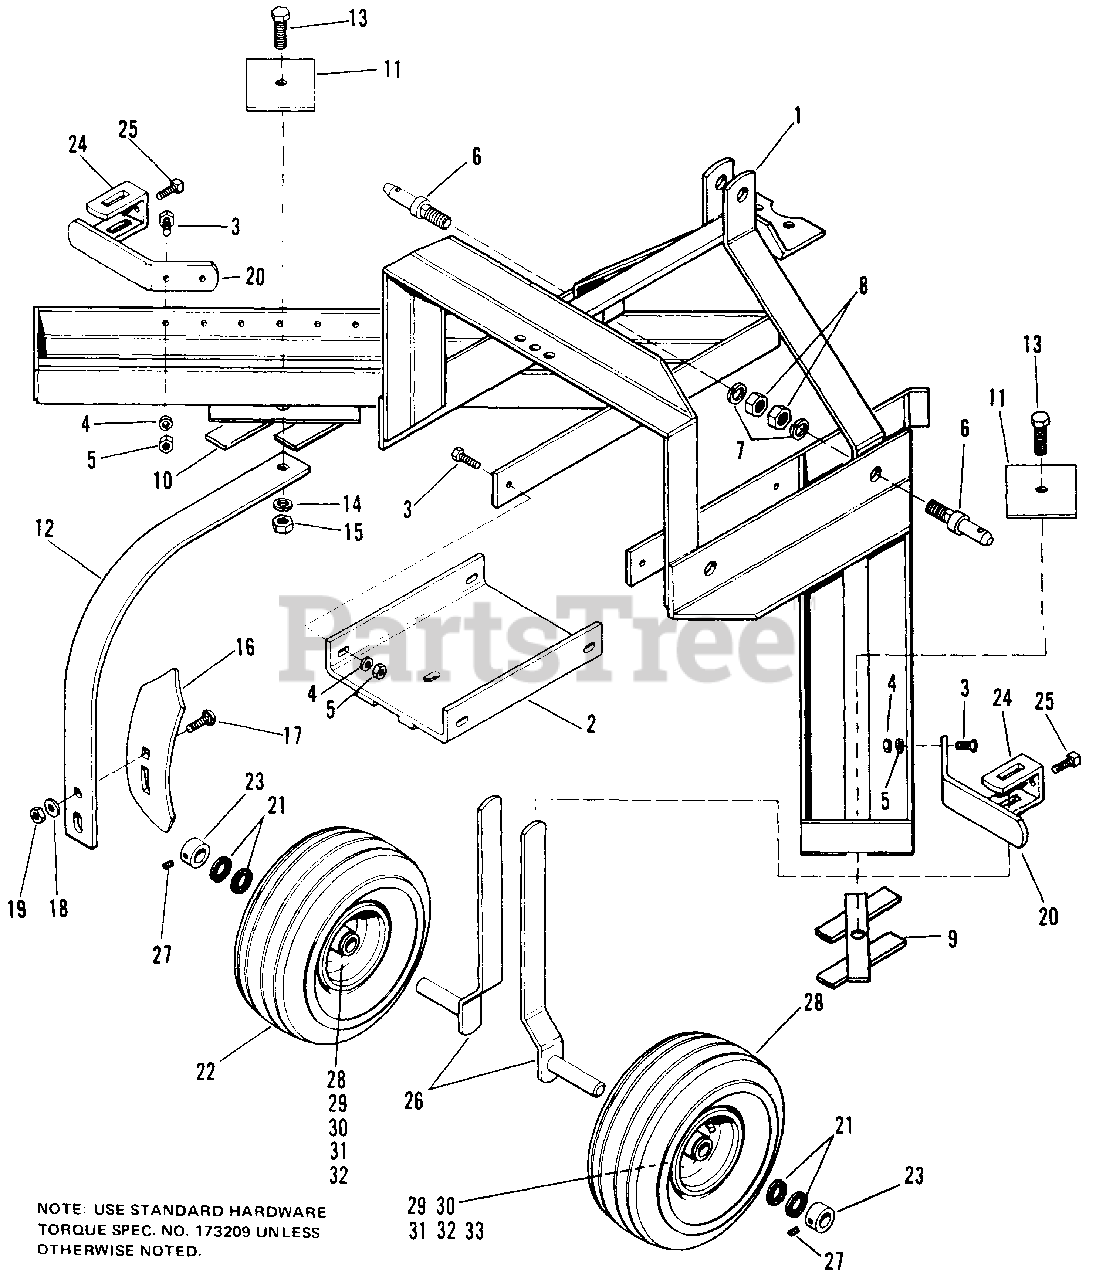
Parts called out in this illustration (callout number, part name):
1	FRAME, Cultivator
2	PLATE ASSY, Support
3	CAPSCREW, Hex Hd., 3/8-16 x 1-1/4
4	LOCKWASHER, Spring, 3/8
5	NUT, Hex, 3/8-16
6	PIN, Hitch
7	LOCKWASHER, Spring, 5/8
8	NUT, Hex, Full, 5/8-11
9	HOLDER ASSY, Shank, R.H.
10	HOLDER ASSY, Shank, L.H.
13	CAPSCREW, Hex Hd., 1/2-13 x 1-1/2
14	LOCKWASHER, Spring, 1/2
15	NUT, Hex, 1/2-13
16	TEETH, Cultivator
17	BOLT, Plow, No. 3, Hd. Reg., 7/16-14 x 1-1/4
18	WASHER, Plain, 7/16
19	NUT, Hex, 7/16-14
21	SEAL, Felt
22	WHEEL & TIRE ASSY, Front
23	COLLAR, Set
24	SHANK, Clamp
25	SCREW, Set, Sq. Hd., Cup Pt., 3/8-16 x 1, Gr. 8
26	STANDARD & SPINDLE ASSY
27	SCREW, Set, Hex, Skt., 5/16-18 x 5/16
28	WHEEL, Front
29	TIRE, 4.10/3.50-4
30	TUBE, 4.10/3.50
32	BEARING, Relief
33	NUT, Special
